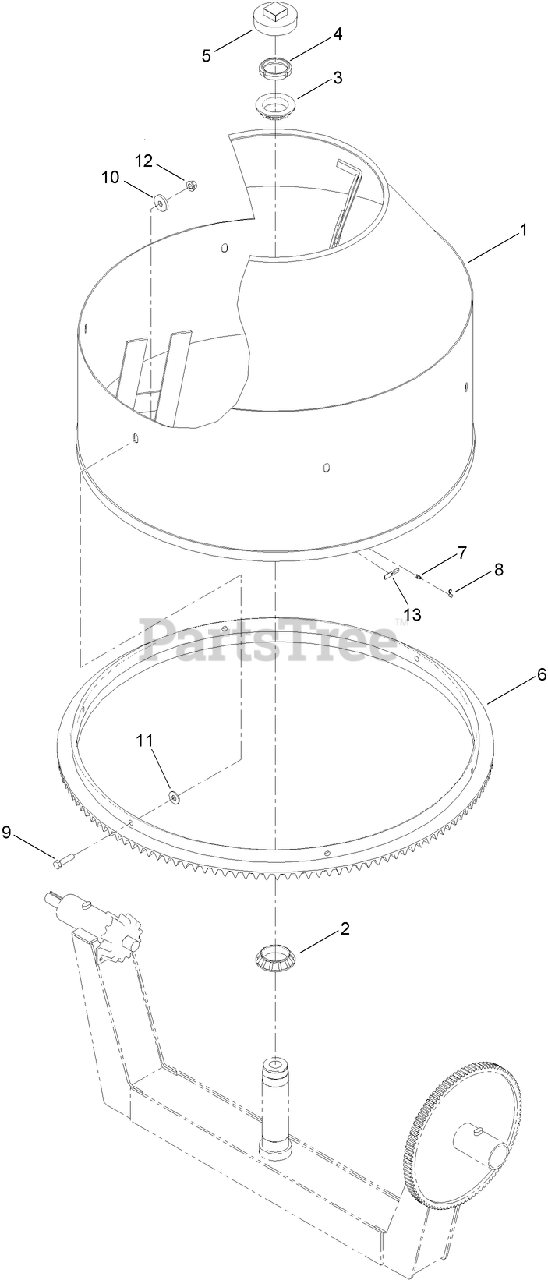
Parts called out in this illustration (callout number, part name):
2	BEARING
3	BEARING
4	NUT-LOCK
5	PLUG-PIPE
6	GEAR-RING
7	FITTING
8	CAP-PLUG
9	SCREW-HH
10	WASHER-FLAT
11	WASHER-FLAT
12	NUT-LOCK
13	DECAL-GREASE
